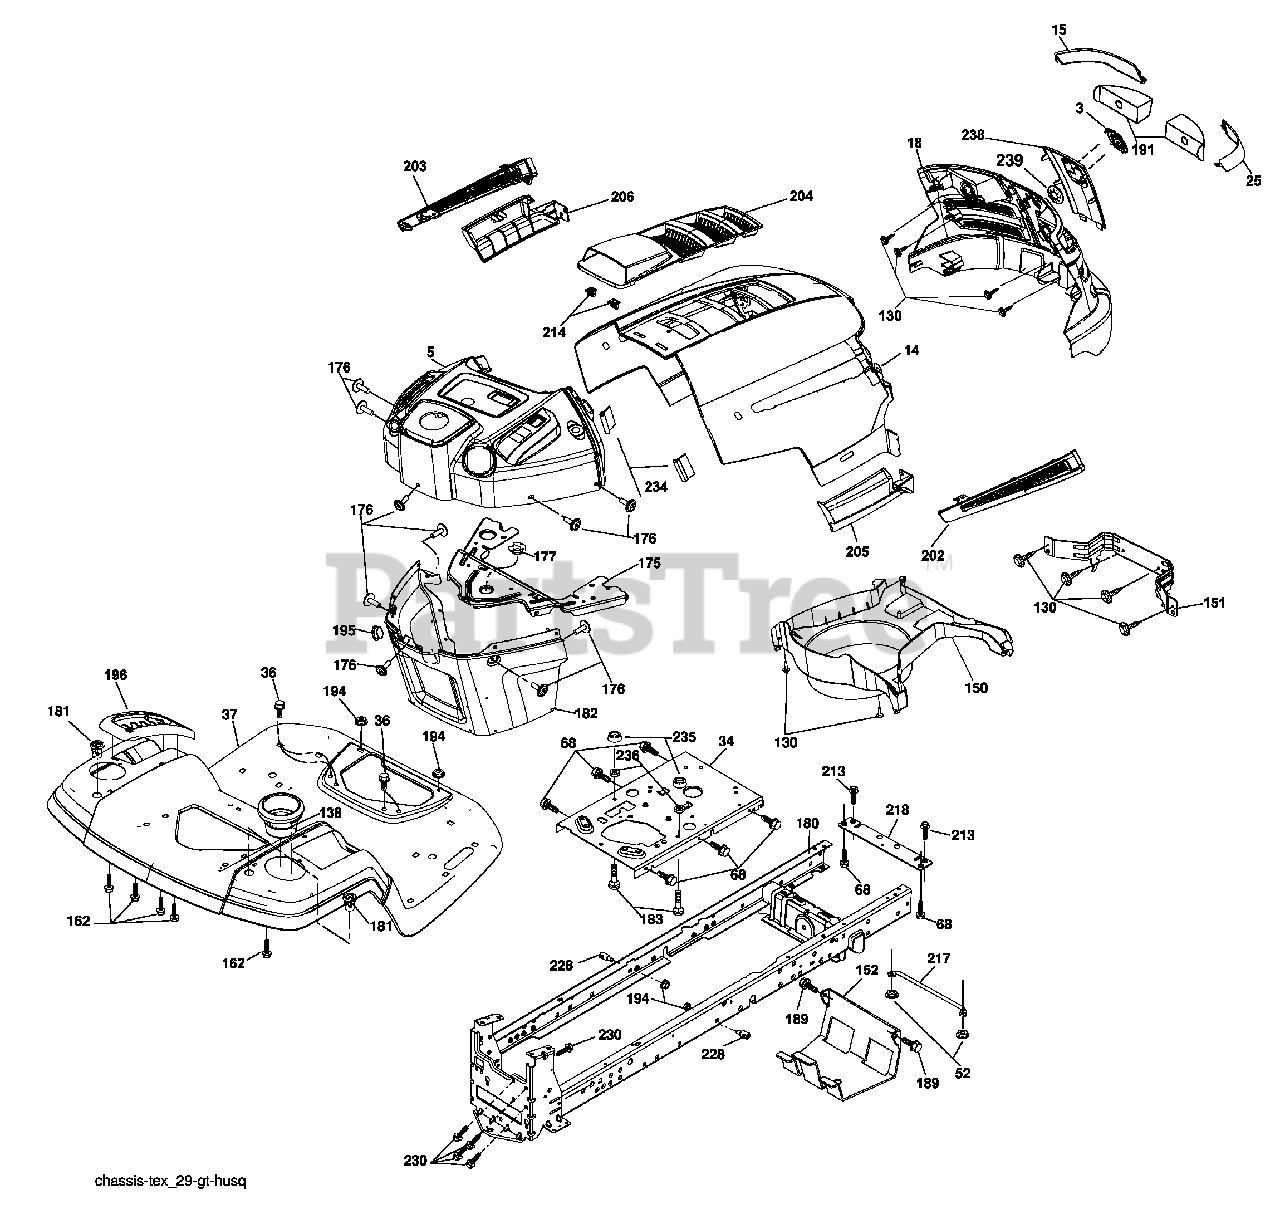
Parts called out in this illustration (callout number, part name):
3	Logo
5	Dash
14	Hood
15	Lens LH
18	Grille/Lens Asm.
25	Lens RH
34	Plate Engine
36	Screw 5/16-18 x 3/4
37	Fender
52	Nut Crown Lock 5/16
68	Screw THDROL 5/16-18 x 1/2
130	Screw 10 x 3/4 Single Lead-Hex
138	Cupholder
151	Bracket Pivot
152	Shield Browning
175	Crossmember
176	Screw 10-24 x 5/8
177	Bushing Steering
180	Chassis
181	Bushing Mtg. Fender Crgo
182	Dash Lower
183	Bolt 5/16-18 UNC x 1-1/4
189	Screw 5/16-18 x 3/4
191	Insert Reflective
194	Nut Lock Hex Flange 5/16-18
195	Plug Dash
196	Console Asm. Deck Lift
202	Vent Side Hood RH
203	Vent Side Hood LH
204	Vent Top Hood
205	Skirt Side RH
206	Skirt Side LH
213	Bolt 5/16-18 x 3/4
214	Clip Retainer
217	Rod Pivot Hood
218	X-Piece Hood Stop
228	Stud Fastener
230	Bolt Shoulder 5/16-18
234	Bumper Hood
235	Spacer Fender
236	Nut Lock 5/16-18 UNC
238	Trim
239	Clip Tinnerman
